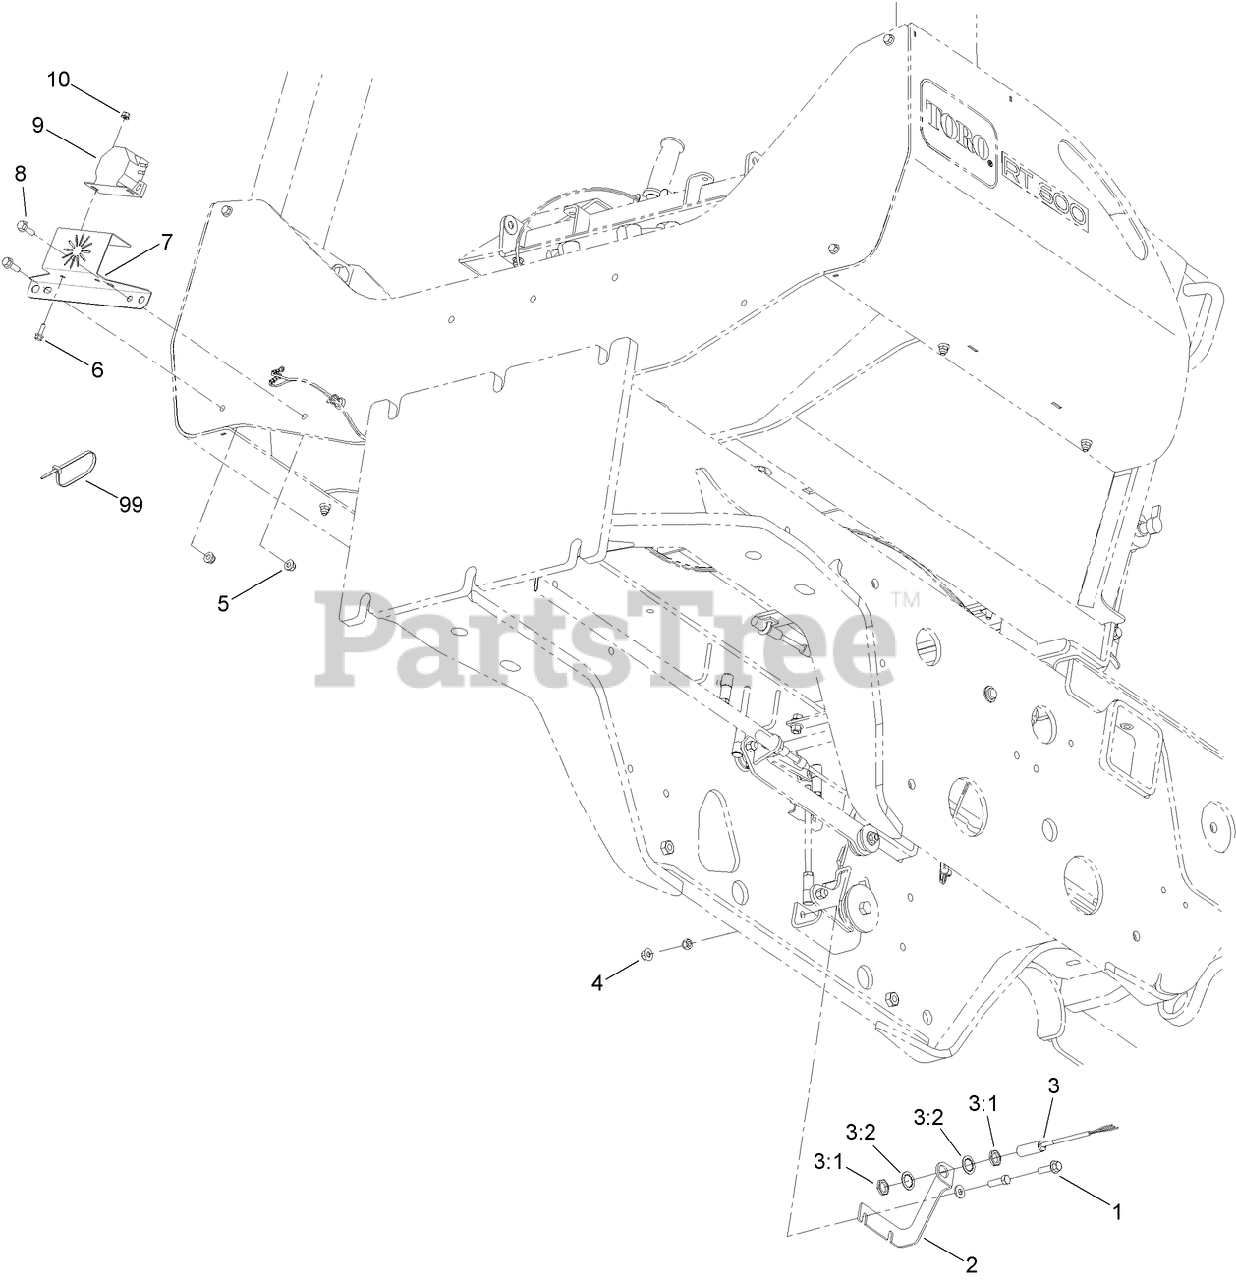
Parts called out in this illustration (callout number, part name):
1	SCREW-HHF
2	BRACKET-SENSOR
3	PROXIMITY SWITCH ASM
3:1	NUT-HEX
3:2	WASHER-LOCK, INTERNAL TOOTH
4	NUT-HEX FLG
5	NUT-LOCK, HHF
6	SCREW-HHF
7	BRACKET-BACKUP ALARM
8	SCREW-HHF
9	ALARM-BACKUP
10	NUT-HHF
99	TIE-CABLE
